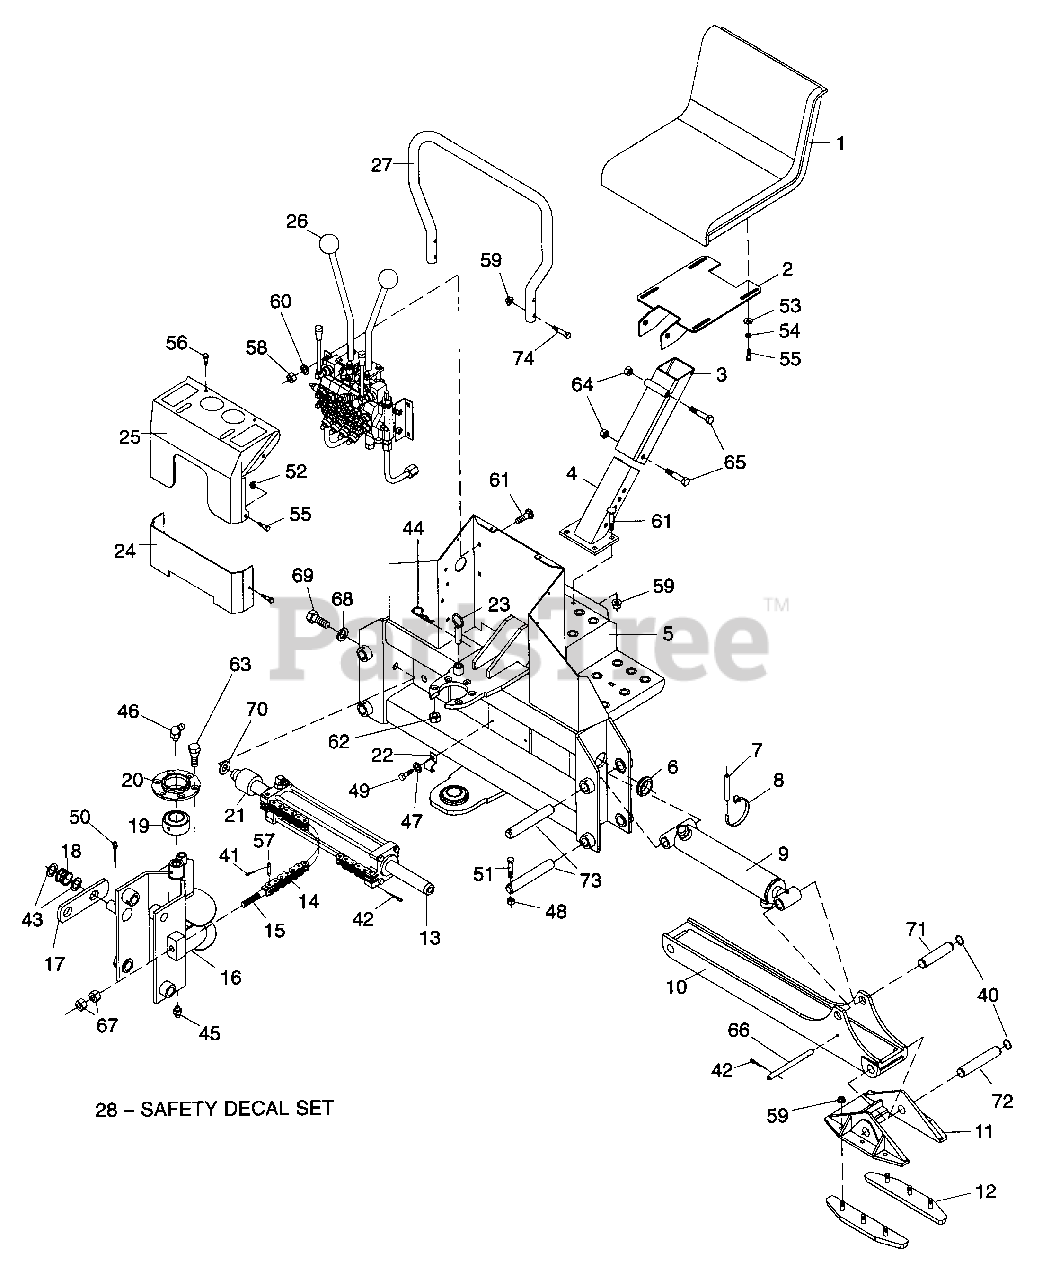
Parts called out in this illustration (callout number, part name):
1	High back seat
2	Seat bracket
3	Upper seat support
4	Lower seat support
5	Main frame
6	Rubber grommet
7	Hose protector shield
8	2-1/2"-3-1/2" Hose clamp
9	Hydraulic cylinder, double-acting 2-1/2 x 11
10	Machined stabilizer arm
11	Machined stabilizer pad
12	Stabilizer rubber pad
13	Hydraulic cylinder, double-acting, 2.50 x 10.63
14	Swing Chain
15	Chain tension bolt
16	Backhoe swing frame
17	Link - .38 x 2.0 x 7.1
18	Spring - Compression 1.19 x .07 x .627
19	1-1/2 ID Ball bushing
20	Cap weld assembly
21	Bumper - 1.25 x 2.25 x 1.75
22	Hose clamp
23	.62 x 3.31 Swing lock pin
24	14 GA x 5.13 x 12.9 Cover
25	Cub Cadet console cover
26	Valve and console assembly
27	1.05 x 13.3 x 15.5 Handle
28	Safety decal set
40	.42 x .925 External retaining ring
41	3/32 x 1/2 Cotter pin
42	3/32 x 1-1/2 Cotter pin
43	10 GA x 1 Bushing
44	3/16 Safety pin
45	1/4-28 Tapered thread grease Fitting
46	45° 1/4 Tapered thread grease fitting
47	1/4 Standard lockwasher
48	1/4 NC Hex locknut
49	1/4 NC x 3/4 Hex head cap screw GR5
50	1/4 x 1-1/2 Cotter pin
51	1/4 NC x 2-1/4 Hex head cap screw GR8
52	5/16 NC Flange locknut
53	5/16 Standard flat washer
54	5/16 Standard lockwasher
55	5/16 NC x 3/4 Hex head cap screw GR5
56	.31 x .75 Sheet metal screw
57	.312 x 1.45 Chain pin
58	3/8 NC Hex nut plated
59	3/8 NC Flange hex locknut
60	3/8 Standard lockwasher
61	3/8 NC x 1 Carriage bolt GR5
62	7/16 NF Hex locknut
63	7/16 NF x 1-1/4 Wheel bolt
64	1/2 NC Hex locknut
65	1/2 NC x 4 Hex head cap screw GR5
66	.50 x 4.45 Headless pin
67	5/8 NC Hex nut
68	3/4 Standard lockwasher
69	3/4 NC x 1-1/2 Hex head cap screw HT
70	13/16 x .010 Shim washer
71	1.0 x 3.88 Headless grooved pin
72	1.0 x 5.84 Headless grooved pin
73	1.00 x 5.92 x 6.31 Drilled bar
74	3/8 NC x 1-1/2 Hex head cap screw GR5
